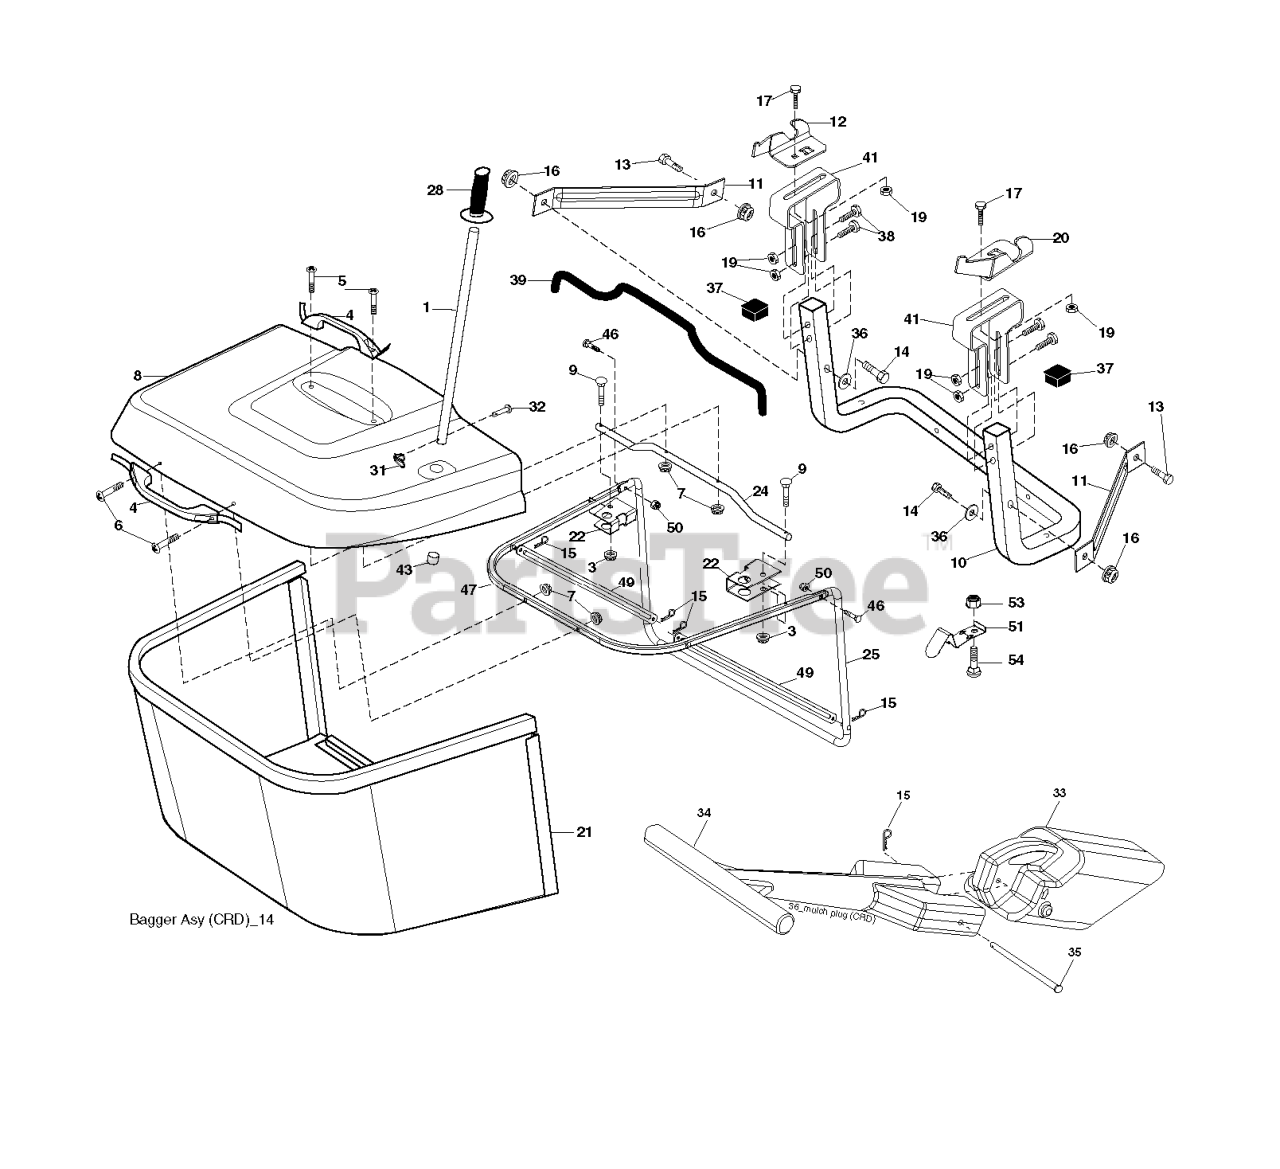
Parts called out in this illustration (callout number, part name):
1	TUBE HANDLE
3	NUT T
4	HANDLE.BAGGER.W/LVRS.BLK.CRD
5	SCREW.PAN.HEAD
6	REPL BY 532 75 00-29
8	COVER.PNT.BGR.CRD.WSLOTS.MS668
9	Bolt Carriage 1/4-20 x 2.25d x Gr.5
10	TUBE
11	BRACKET.SUPPORT.UPPER.BAG.CRD
12	BRKT PIVOT
14	BOLT-HEX EAK
15	RETAINER-SPRNG RB
16	NUT LOCK FLG 3/8-16 UNC
17	RP BOLT 5/16-18 X3/4 ZN/YEL GR
19	NUT LOCK HEX FLANGE 5/16-18
20	BRKT.PIVOT.RH.CRD
21	BAGGER.ASM.CRD.2007
22	BRKT.SIDE.BAG.CRD
24	TUBE.PIVOT.BAG.CRD.BLACK
25	PIPE
28	GRIP.HANDLE.BLACK
31	RETAINER CLIP
32	RIVET,DRILLED
33	PLUG.MULCHER.92 CRD
34	HANDLE.MULCHER.92.CRD (2 2)
36	WASHER
37	Plug Support Bagger CRD
38	BOLT.5/16-18X2.5
39	SEAL.TRIM.37'
41	BRKT.VERT.ADJ.BAGGER.CRD
43	PLUG, TUBING END
46	BOLT.CARRIAGE.5/16-18
47	PIPE
49	ROD
50	NUT.71038.31-18.HEX.NYLOCK
51	LATCH
53	NUT
54	BOLT
